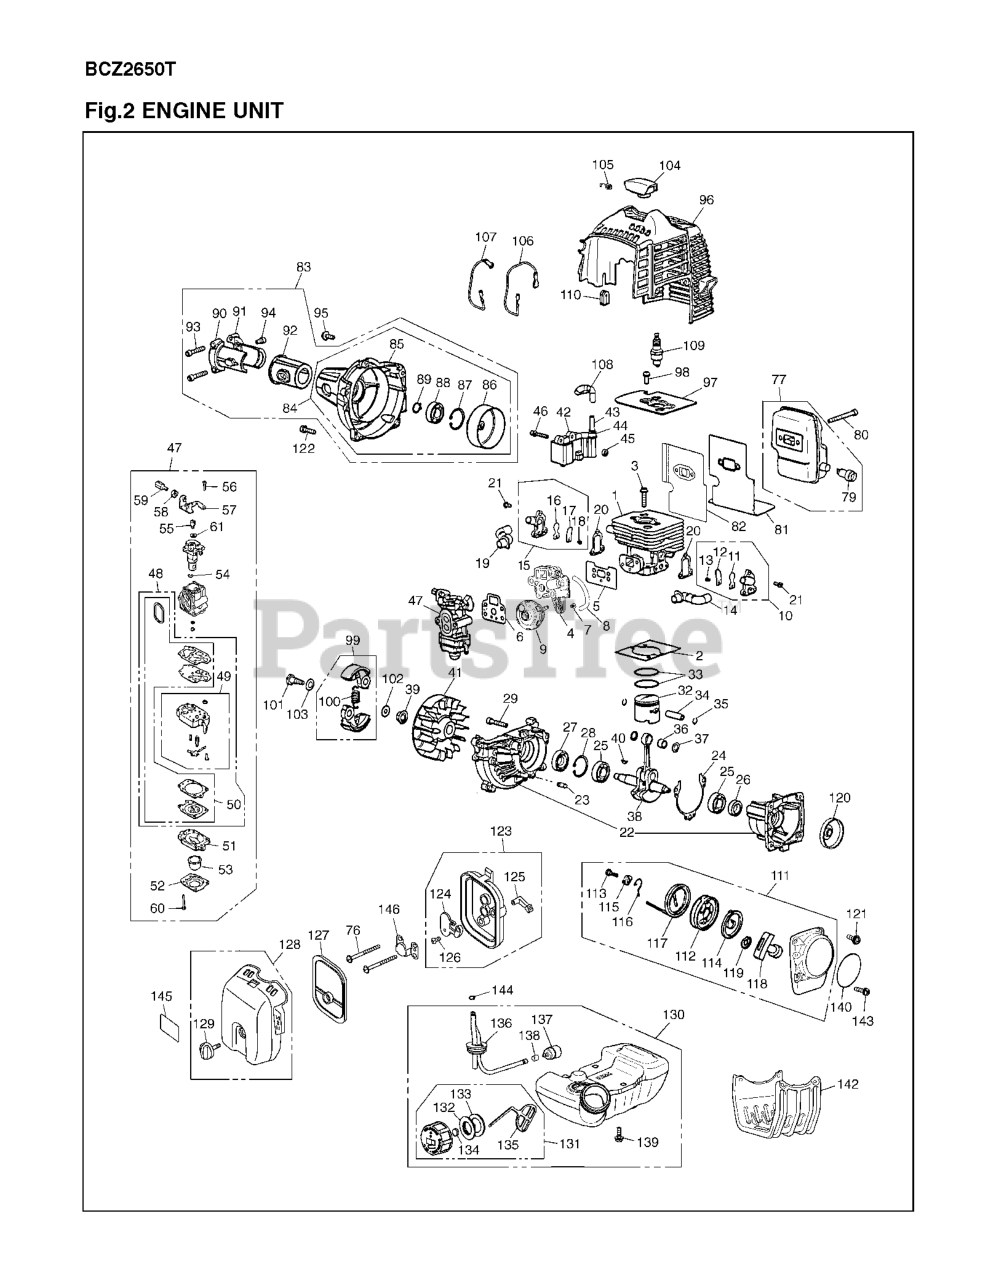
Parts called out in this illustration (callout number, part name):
1	CYLINDER
2	GASKET, BASE
3	BOLT
4	INSULATOR
5	GASKET, INSULATOR
6	GASKET, CARB (RPLS T155113131)
9	PUMP ASSY
10	AIR CHECKER (S) ASSY
11	REEDVALVE
14	PIPE AIR (S)
15	AIR CHECKER (F) ASSY
16	REEDVALVE
19	PIPE AIR (F)
20	GASKET, VALVE
22	CRANKCASE-C
23	PIN
24	GASKET.CASE
27	SEAL
34	PIN (RPLS T151341310)
38	CRANKSHAFT COMP(RPLS481042000)
39	NUT
40	KEY
42	COIL-A
44	CAP
45	SPACER
47	CARBURETOR ASSY
48	REBUILD KIT
49	CARBURETOR BODY
50	GASKET KIT
51	BODY CARB
52	1OVER
54	RING
55	SWIVEL
56	SCREW
57	BRACKET
58	NUT
59	ADJUSTER
61	WASHER
77	MUFFLER
79	ARRESTER
82	PLATE, MUFFLER
83	COVER ASSY
84	COVER COMP. (R-31100&31101)
85	COVER.FAN
86	DRUM (RPLS 481031120-22)
88	BEARING
90	BRACKET(A)-24
91	BRACKET(B)-24
94	BOLT M5X14
96	COVER, ENGINE
99	SHOE-C
107	CORD.EARTH
108	TUBE (RPLS 263072210)
109	PLUG CMR7H
111	RECOIL-A
114	SPRING, SPIRAL
115	COLLAR
116	SWING ARM
119	PLATE.STOPPER
121	BOLT M5X14
122	BOLT
123	BODY - A
124	PLATE, CHOKE
126	SCREW
127	ELEMENT
128	%CLEANER COVER ASSY
129	Cleaner Knob
131	CAP A
132	HOLDER-A
136	PIPE-C
138	CLIP
140	LABEL, RECOIL
143	BOLT
144	CLIP
